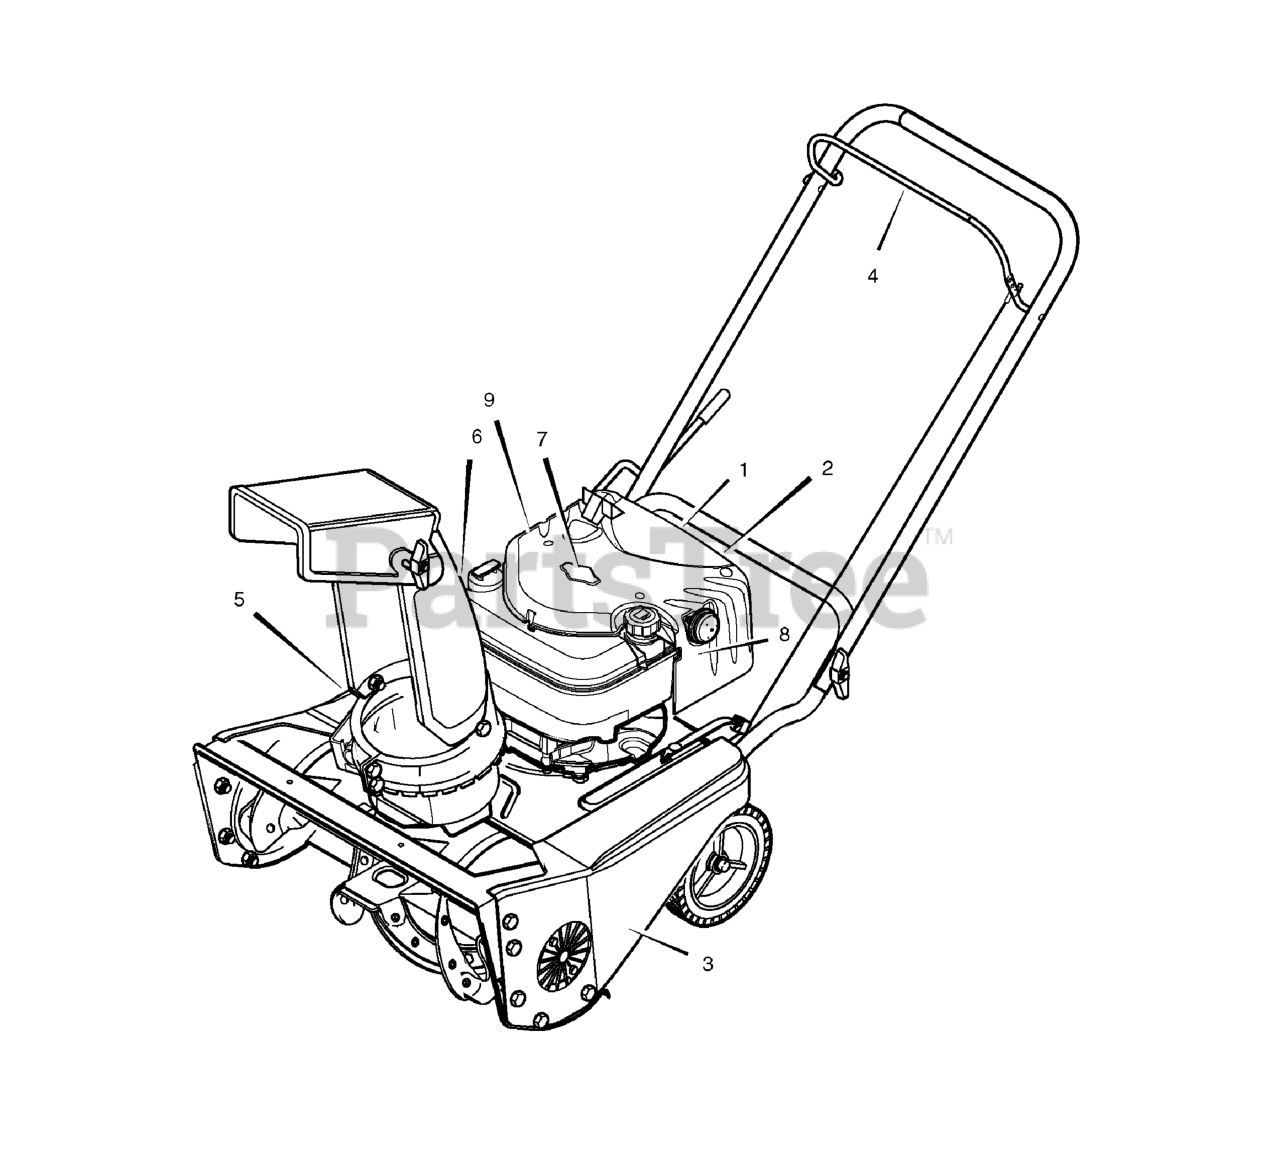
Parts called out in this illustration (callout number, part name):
1	Decal, 4hp / 21"
2	Decal, Choke
3	Decal, Belt Instruction (inside cover)
4	Decal, Auger Control Lever
5	Decal, Danger Auger (Foot)
6	Decal, Danger Chute (Hand)
7	Decal, Briggs & Stratton
8	Decal, Primer Bulb
9	Decal, Hot Surface
